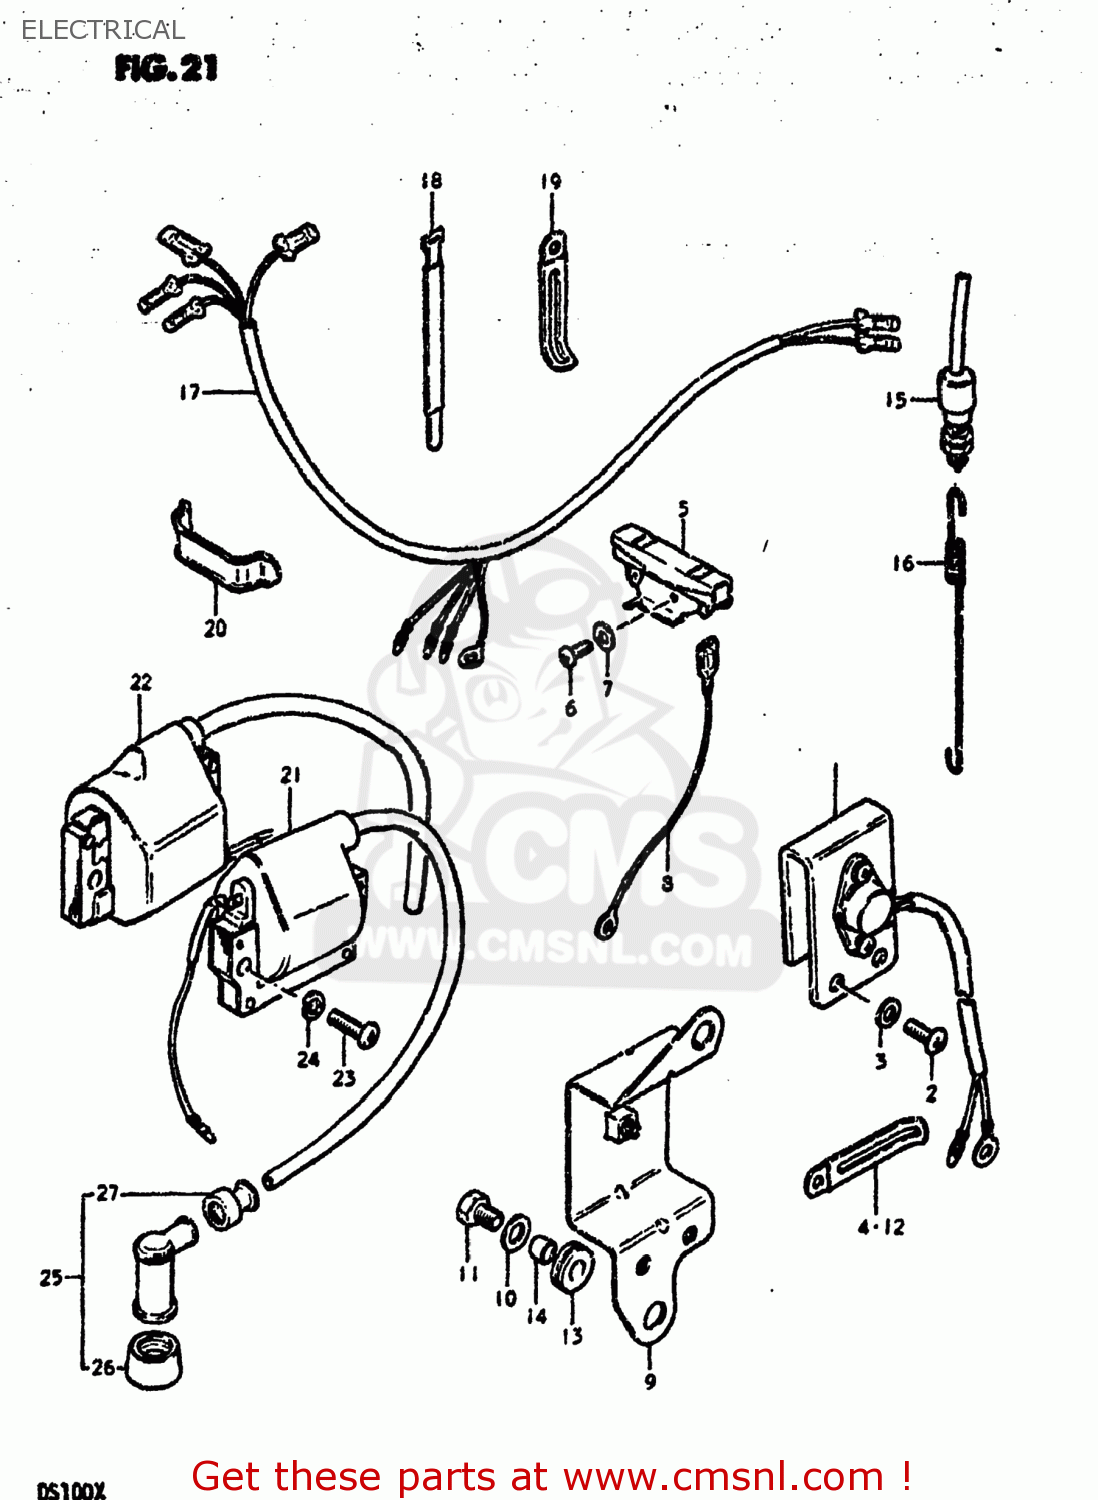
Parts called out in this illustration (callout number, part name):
1	REGULATOR ASSEMBLY
2	SCREW 6X12
3	WASHER
4	CLAMP L:35
5	RESISTOR ASSY,MAGNETO
6	SCREW
7	WASHER
8	WIRE
9	BRACKET
10	WASHER (6.5X20X1.2)
11	BOLT, UPPER
12	CLAMP
13	CUSHION
14	SPACER (7X9X7)
15	SWITCH ASSY, STOP LAMP
16	SPRING
17	HARNESS,WIRING
18	CLAMP
19	CLAMP
20	CLAMP
21	COIL ASSEMBLY,IGNITION
22	UNIT & COIL ASSEMBLY,IGNITION
23	SCREW
24	LOCK WASHER
25	CAP,SPARK PLUG
26	SEAL,SPARK PLUG
27	SEAL,SPARK PLU
